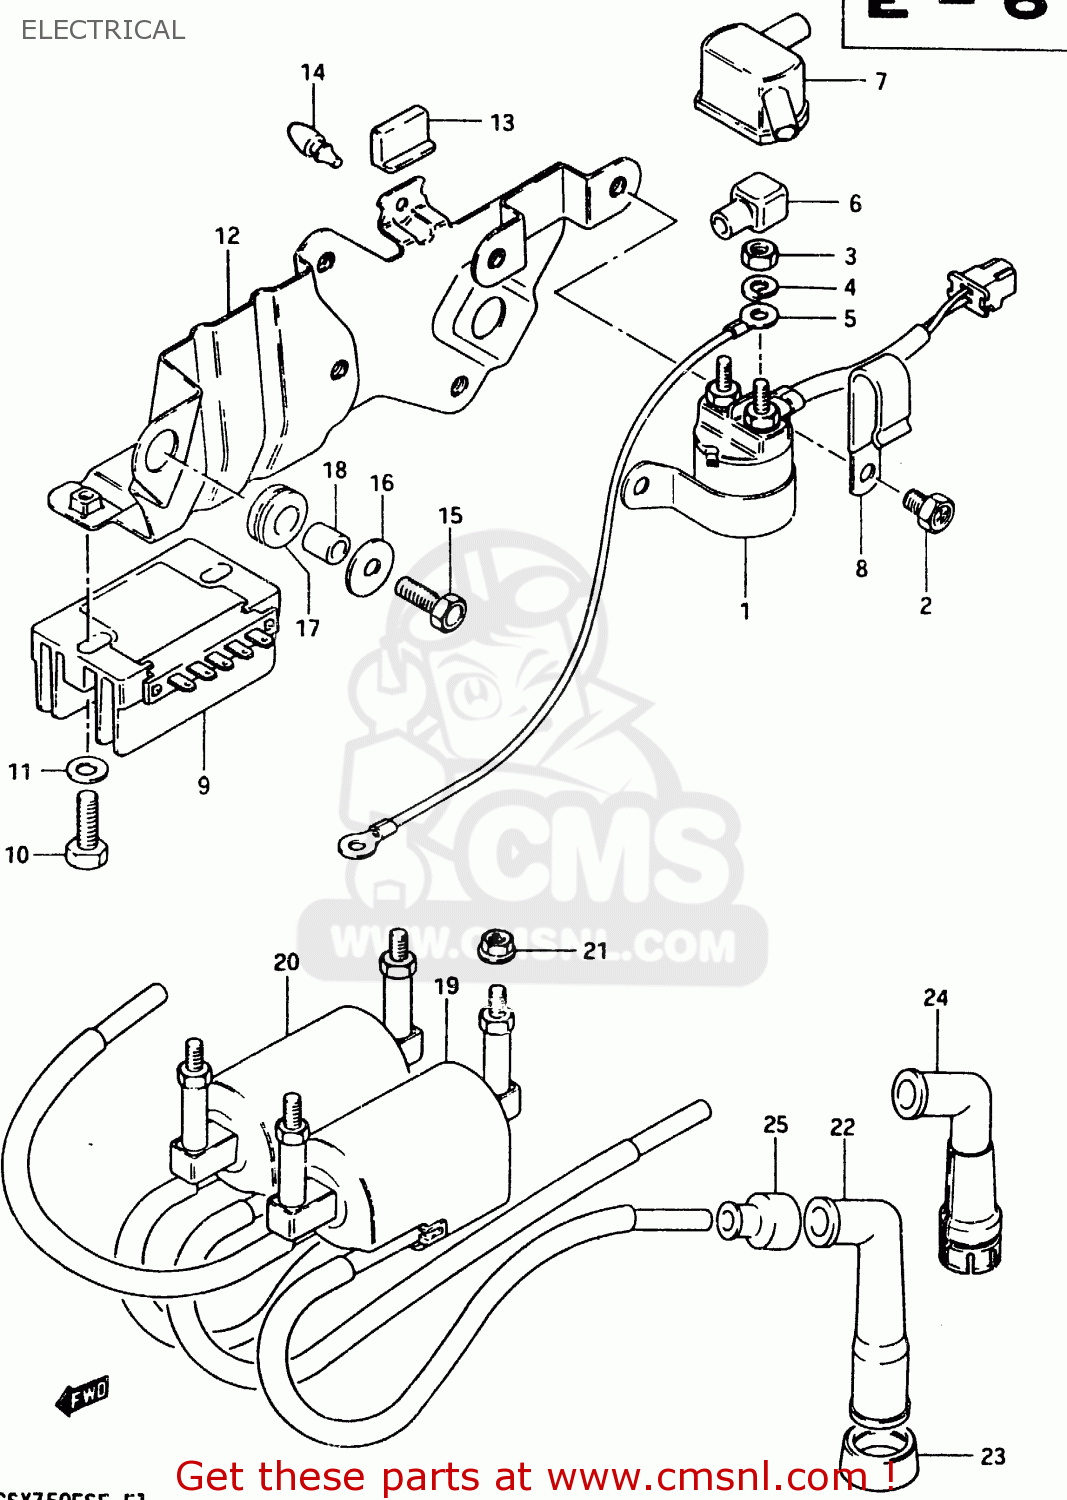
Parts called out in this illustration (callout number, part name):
1	RELAY ASSEMBLY,STARTING MOTOR
2	SCREW(6X10)
3	NUT
4	WASHER,LOCK
5	WIRE,STARTER MOTOR LEAD
6	CAP,STARTER MOTOR TERMINAL
7	CAP,STARTER RELAY TERMINAL
8	CLAMP
9	RECTIFIER ASSEMBLY
10	BOLT(6X20)
11	WASHER
12	PLATE,ELECTRIC PARTS H
13	CUSHION,FRAME COVER
14	CUSHION
15	BOLT, UPPER
16	WASHER (6.5X20X1.2)
17	CUSHION
18	SPACER(6.1X9X7.5)
19	COIL ASSEMBLY,IGNITION
20	COIL ASSEMBLY,IGNITION NO
21	NUT
22	CAP,SPARK PLUG
23	SEAL,SPARK PLUG
24	CAP, SPARK PLUG
25	SEAL,SPARK PLU
